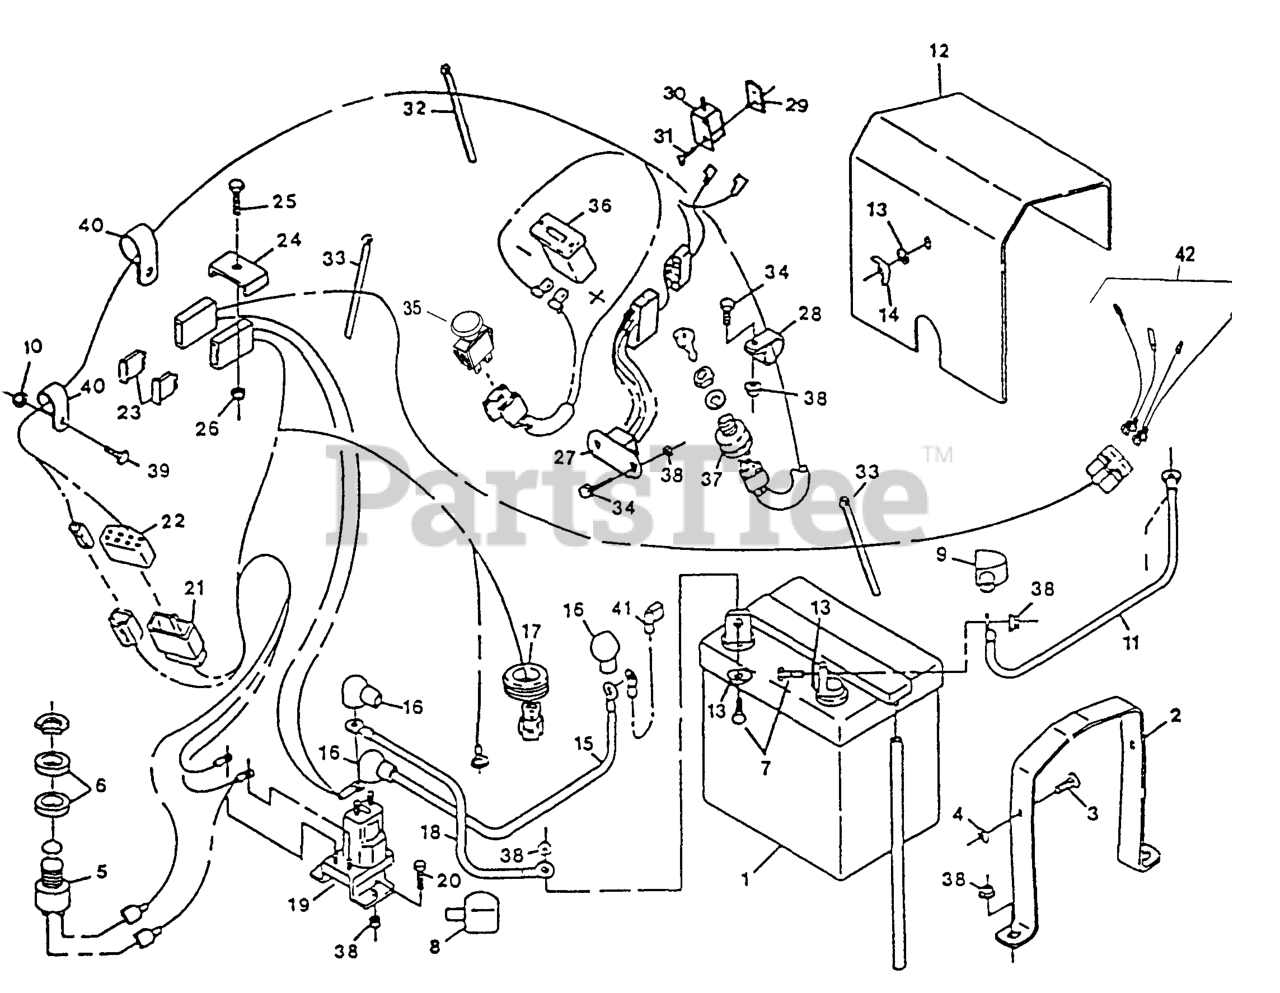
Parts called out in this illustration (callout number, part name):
1	Battery, 12v Manifold
2	STRAP,BATTERY HOLDDOWN
3	BOLT-CARR
4	NUT-RETAINING
5	SWITCH,PUSH BUTTON
9	INSULATOR, BATTERY -
11	WIRE-GROUND
14	NUT-WING
16	INSULATOR-SOLENOID
17	GROMMET
21	HARNESS,WIRING HYDRO
22	HARNESS,CONSOLE-TT
23	FUSE-BLADE TYPE, 20 AMP
24	CLIP-FUSE BLOCK PLTD
27	MODULE-OPC NO TIME DELAY
28	CLIP-LOOM
29	PLATE-TAPPED
30	SWITCH-OPEN, NORMALLY
32	TIE-PLASTIC
33	TIE-CABLE
36	METER-HOUR
37	SWITCH,IGNITION
40	CLIP-LOOM
42	HARNESS,WIRING 19KA
